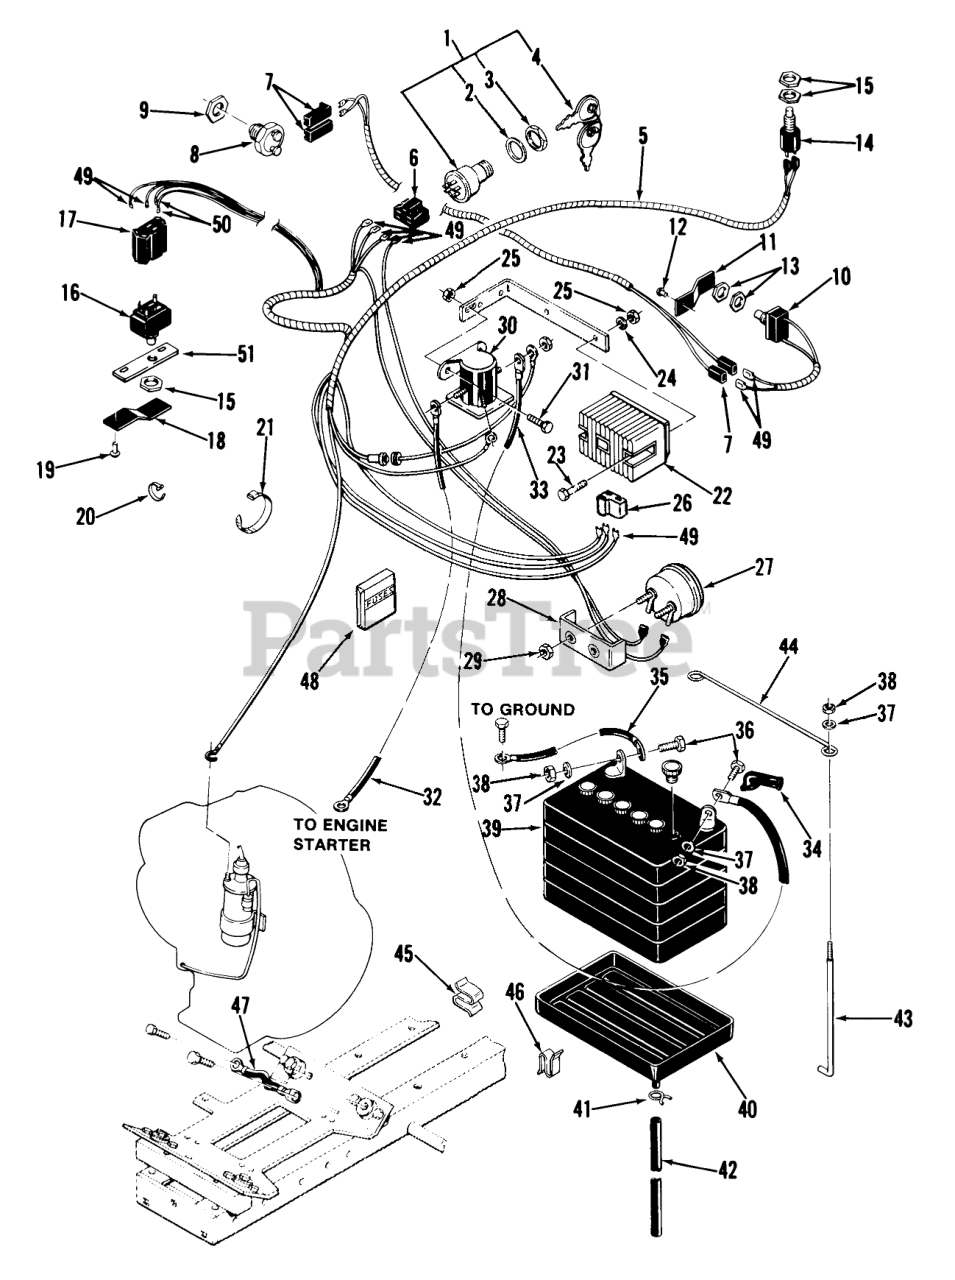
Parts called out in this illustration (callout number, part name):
1	SWITCH-IGNITION
2	LOCKWASHER
4	Key-EL
5	Wiring Harness
6	CONNECTOR-5 WAY-SERV
7	CONNECTOR BODY
8	SWITCH-INTERLOK CLUT
9	NUT-SPECIAL 9/16-18
10	Interlock Switch-Transmission
11	CLIP-SWITCH
12	RIVET
13	NUT-HEX
14	SWITCH
15	NUT-HEX
16	SWITCH-CLUTCH
17	CONNECTOR 5 WAY
18	CLIP-SWITCH
19	RIVET
20	Cable Tie
21	PLASTIC TIE
22	REGULATOR-RECTIFIER
23	Bolt
24	LOCKWASHER
25	Nut
26	CONNECTOR
27	AMMETER W/CLAMP
28	Clamp
29	HEX NUT 10-32 E.S.
30	SOLENOID
31	Screw
32	WIRE-GROUND
33	Cable
34	Terminal Cover
35	Wire
36	Bolt
38	Nut
39	Battery
40	TRAY-BATTERY
41	Clamp
42	FUEL HOSE 13" OF 6554
43	Hook
44	ROD-HOLD DOWN
45	SPEED CLIP
46	CLIP
47	WIRE-GROUND
48	Fuses 3AG 25AMP
49	Terminal
50	TERMINAL-TAB RCPT
51	CLAMP-PTO SWITCH
